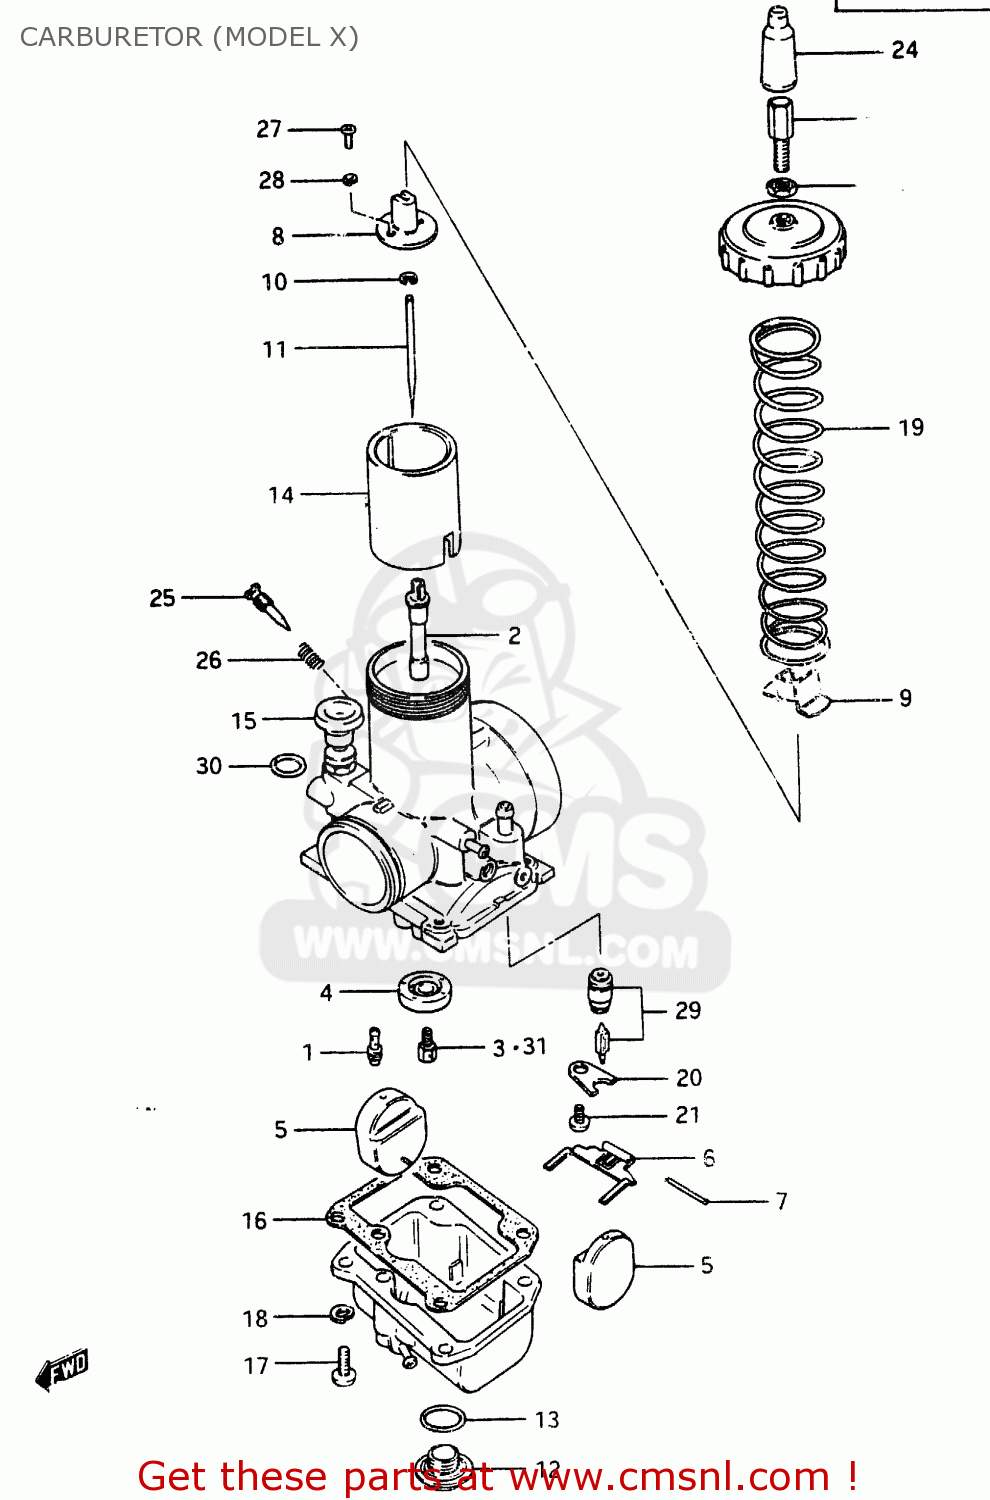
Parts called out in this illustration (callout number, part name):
1	JET,PILOT
2	JET,NEEDLE
3	JET
4	RING,MAIN JET FIXING
5	FLOAT
6	ARM,FLOAT
7	PIN,FLOAT
8	CONNECTOR
9	COVER,HOLDER
10	CLIP
11	NEEDLE JET
12	PLUG
13	O RING(D:1.5,ID:19.5)
14	VALVE,THROTTLE
15	VALVE ASSEMBLY,STARTER
16	GASKET,FLOAT CAHMBER (NAS)
17	SCREW
18	LOCK WASHER
19	SPRING
20	PLATE
21	SCREW 4X6
22	ADJUSTER,CABLE
23	NUT
24	CAP,CABLE ADJUSTER
25	SCREW,PILOT AIR
26	SPRING
27	SCREW
28	LOCK WASHER
29	VALVE ASSEMBLY,NEEDLE
30	O-RING
31	JET
